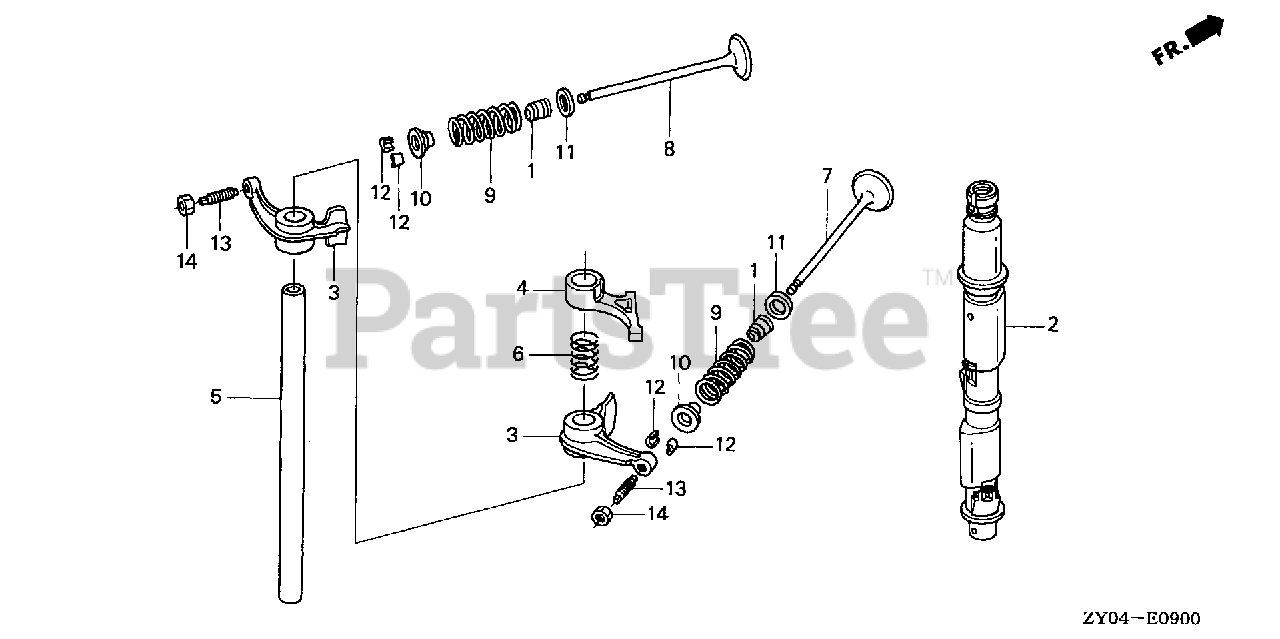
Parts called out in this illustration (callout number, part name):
1	SEAL, VALVE STEM (ARAI)
3	ARM, VALVE ROCKER
4	ARM, FUEL PUMP ROCKER
5	SHAFT, ROCKER ARM
6	SPRING, ROCKER ARM
7	VALVE, IN.
8	VALVE, EX.
9	SPRING, VALVE
10	RETAINER, VALVE SPRING
11	SEAT, VALVE SPRING
12	COTTER, VALVE
13	SCREW, TAPPET ADJUSTING
14	NUT, TAPPET ADJUSTING
